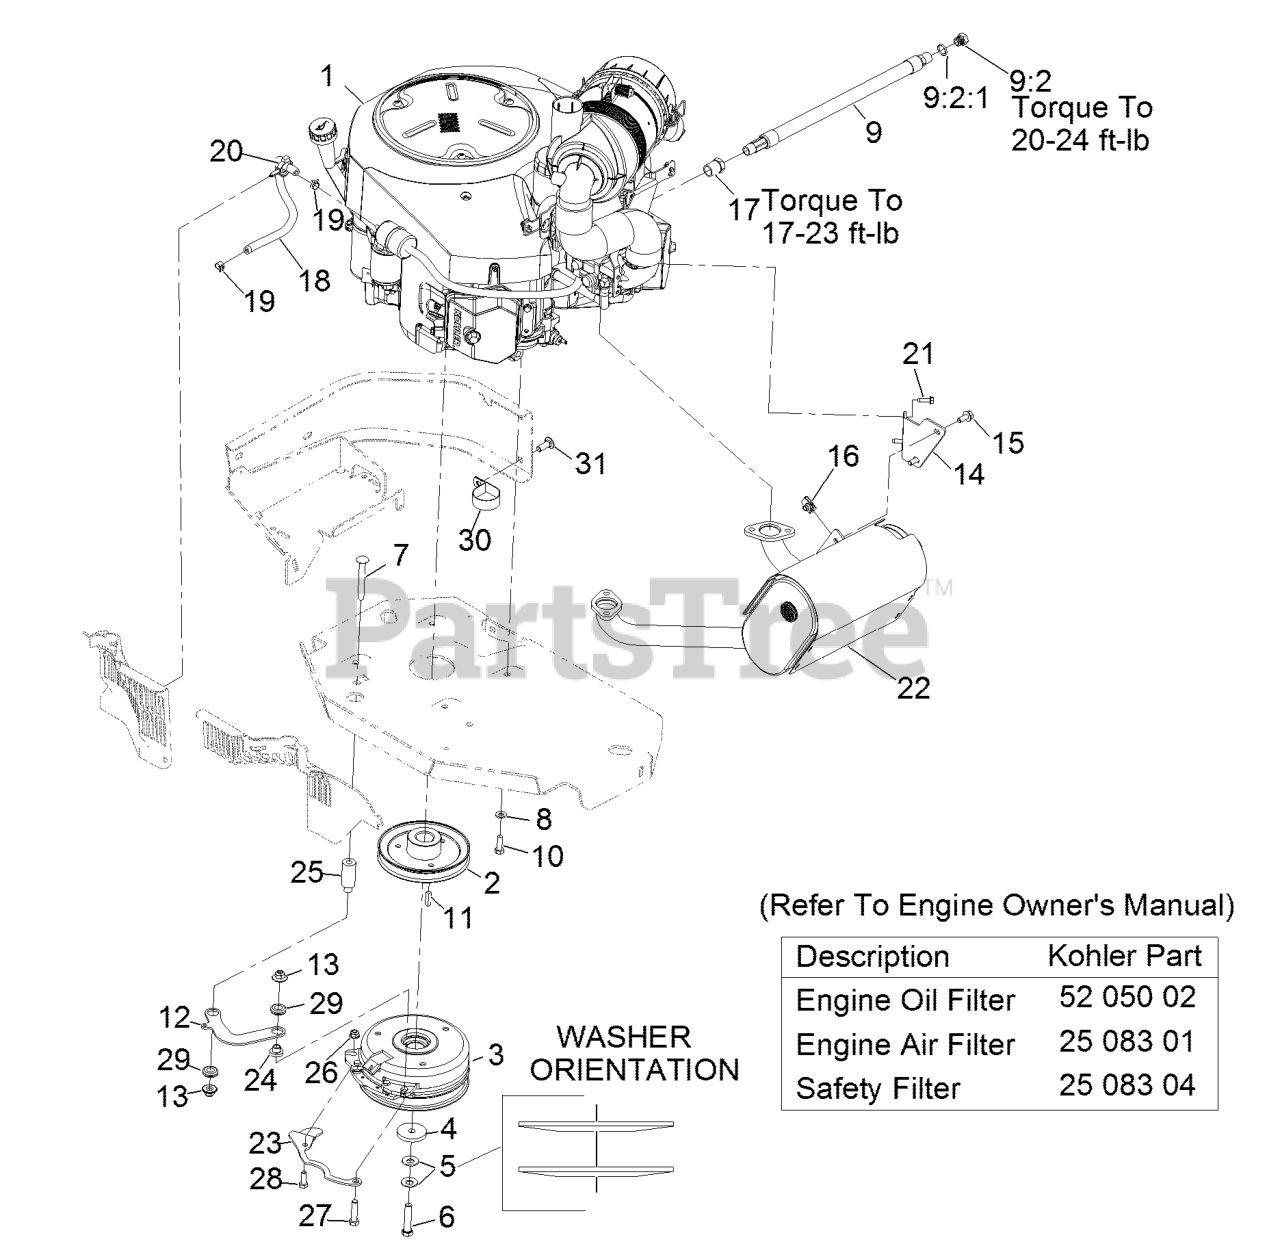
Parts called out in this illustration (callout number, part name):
2	SHEAVE
4	WASHER-CLUTCH
5	WASHER-SPRING
6	SCREW-HH W/LOCTITE
7	SCREW-CARR
8	WASHER-SPRING
9	OIL DRAIN HOSE ASM
9:2	PLUG-HH
9:2:1	O-RING
10	SCREW-HH
12	LINK-ANCHOR, CLUTCH
13	Nut-Nyloc 3/8-16 Flg
15	SCREW-HHF
17	BUSHING
19	CLAMP-HOSE
20	CLAMP-HOSE
22	MUFFLER
23	BELT-GUIDE
26	NUT-HF, NI
27	SCREW-HH
28	SCREW-HH
29	GROMMET-RUBBER
30	CLAMP-R
31	SCREW-CARR
